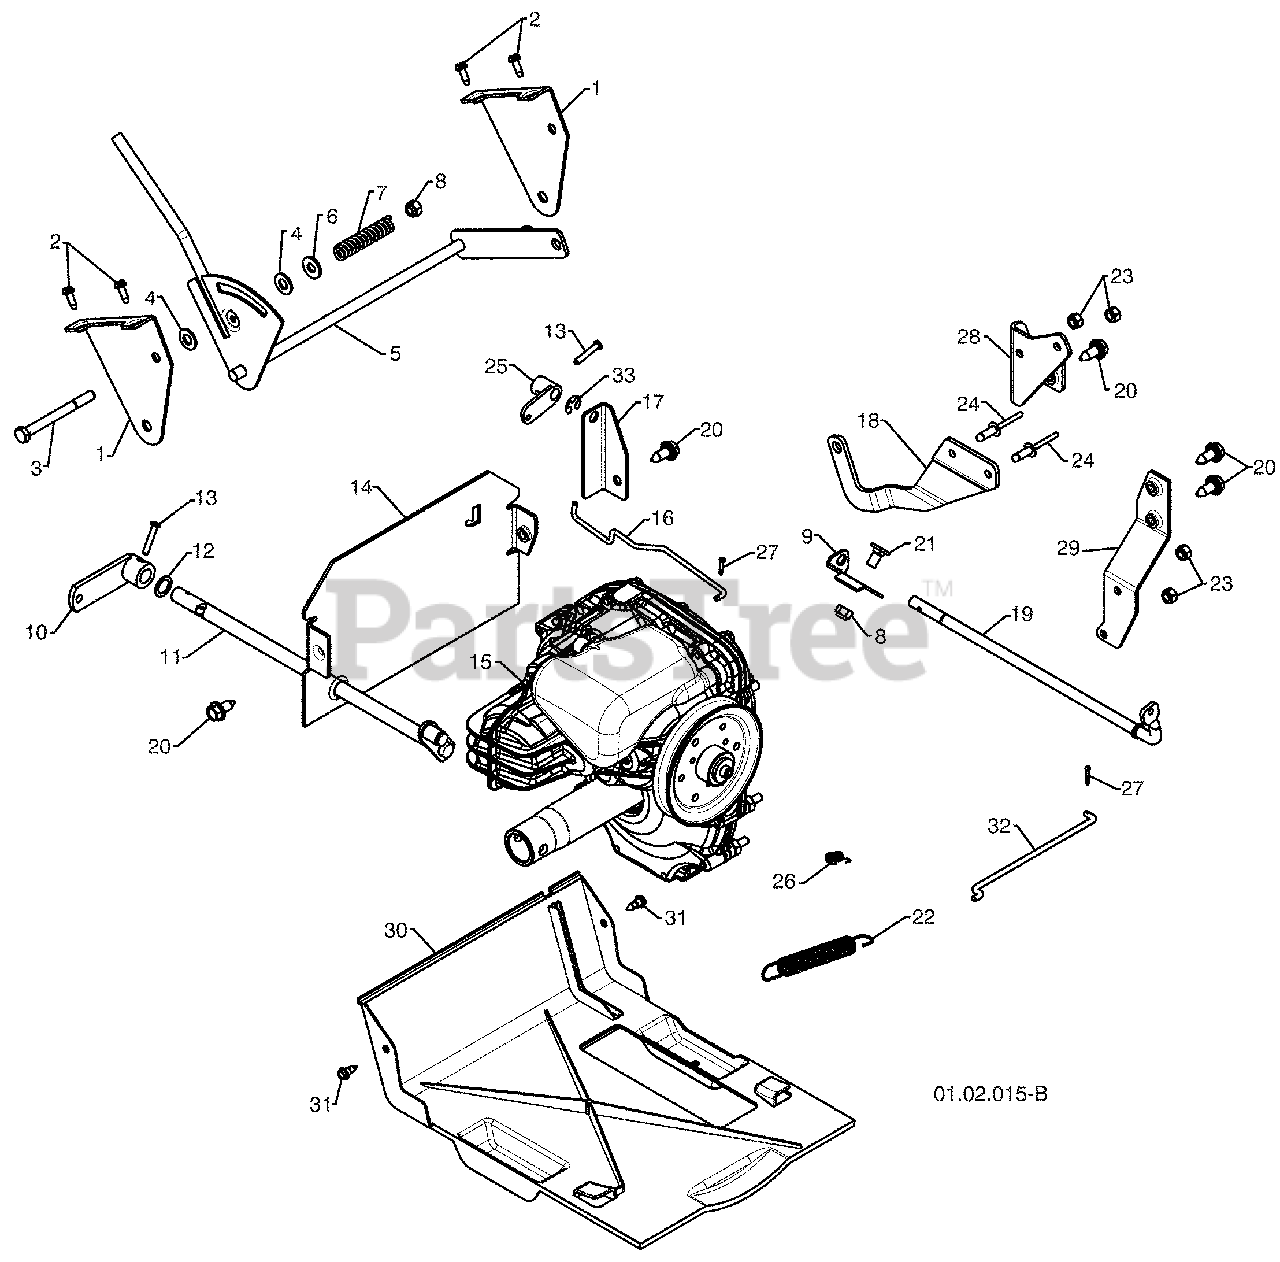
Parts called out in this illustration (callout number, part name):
1	SHIFT BRACKET
2	SCREW 10-24 X .625
3	SCREW 5/16-18 X 3.25
4	PLASTIC WASHER
5	SHIFT ASSEMBLY
7	FRICTION SPRING
8	NUT 5/16-18
9	FRONT CLUTCH BRACKET
10	CONTROL ARM
11	CONTROL SHAFT
13	CLEVIS PIN
14	REAR PLATE
15	TRANSMISSION
17	REAR CLUTCH BRACKET
18	CONTROL ARM
19	CLUTCH SHAFT
20	SCREW 5/16-18 X .750
21	CARRIAGE BOLT 5/16-18 X .625
22	BRAKE SPRING
23	NUT 1/4-20
24	POP RIVET 1/4 X .475
25	CLUTCH ARM
26	TRACTION SPRING
27	RETAINER CLIP
28	ANTI-ROTATE BRACKET
29	TORQUE STRAP BRACKET
30	BOTTOM PAN
31	SCREW 10-24 X .625
32	CLUTCH ROD
33	E-RING .375
